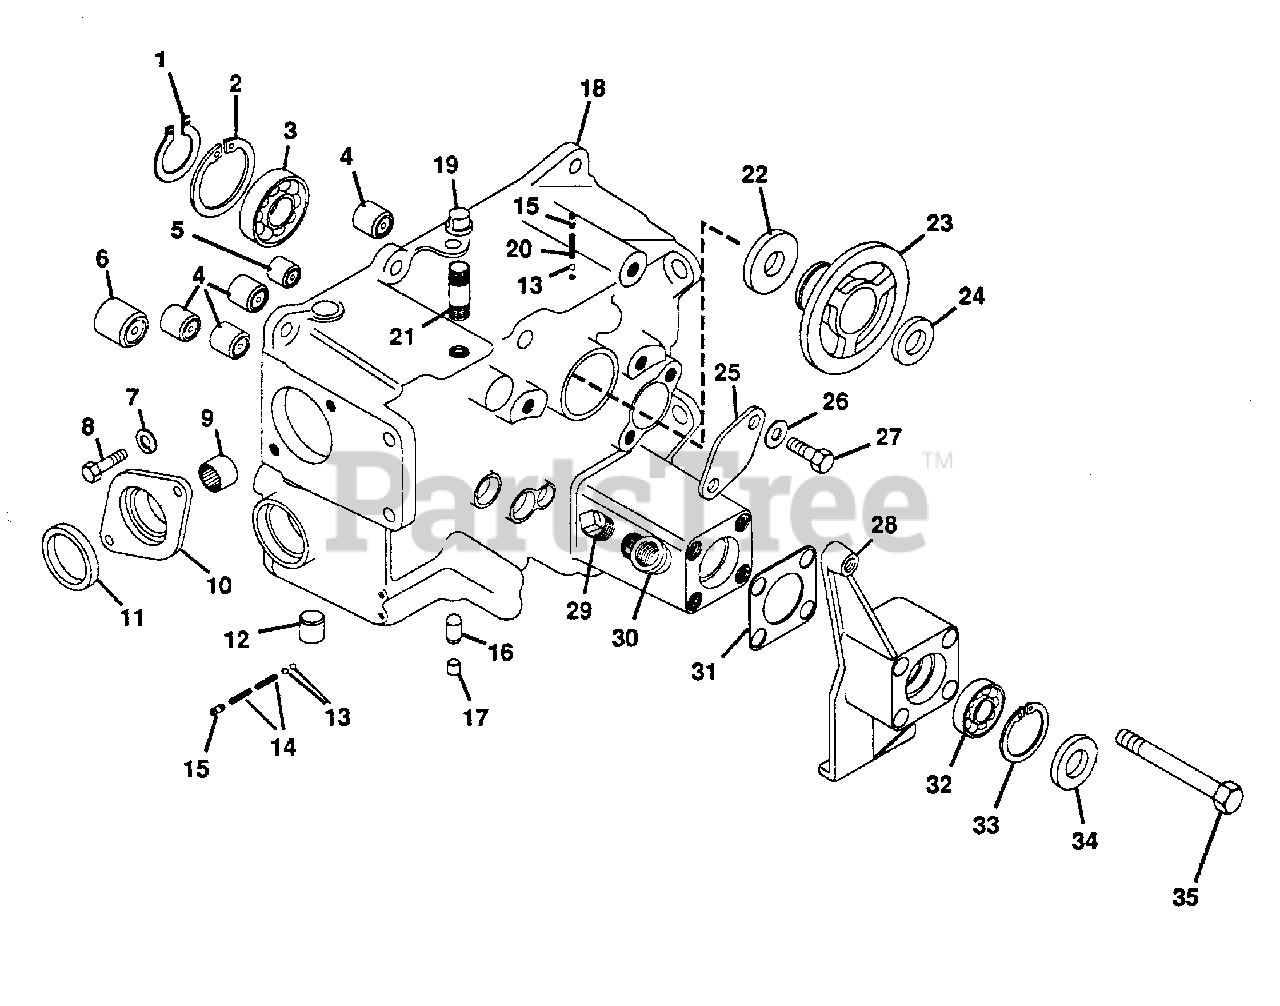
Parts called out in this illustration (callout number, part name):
1	RING, RETAINING 1.969 SHAFT
2	RING, RETAINING 3.156 BORE
3	BEARING, BALL 1.968X3.149X.629
4	BEARING, NEEDLE .75X1X.75
5	BEARING, NEEDLE .625X.812X.750
6	BRG, NEEDLE 1.000X1.250X.750
7	WASHER, LOCK 5/16 REG.
8	BOLT, HEX 5/16-18X1.00
9	BEARING
10	CAP, FRONT PTO
11	SEAL, OIL .750X1.254X.188
12	PLUG
13	BALL, STEEL 5/16
14	SPRING, COMP. 1.50X.30X26 LB/IN
15	PLUG, PIPE 1/8
16	PIN, INTERLOCK
17	PLUG, CUP 3/8
18	ASSEMBLY, TRANSMISSION CASE
19	CAP, PIPE 1/2 NPT
20	SPRING
21	NIPPLE, PIPE 1/2X2.5
22	SEAL, OIL 2.250X3.005X.375
23	HUB, CLUTCH
24	SEAL, OIL .75X1.625X.25
25	PLATE, COVER
26	WASHER, FLAT .406X.812X.065
27	BOLT, HEX 3/8-16X.750
28	RETAINER, AXLE BEARING
29	PLUG, PIPE 1/2
30	ELBOW, 1/2 90 DEGREE STREET
31	GASKET
32	BEARING, BALL 1.250X2.250X.500
33	RING, RETAINING
34	SEAL, OIL AXLE
35	BOLT, HEX 1/2-13X3.25
